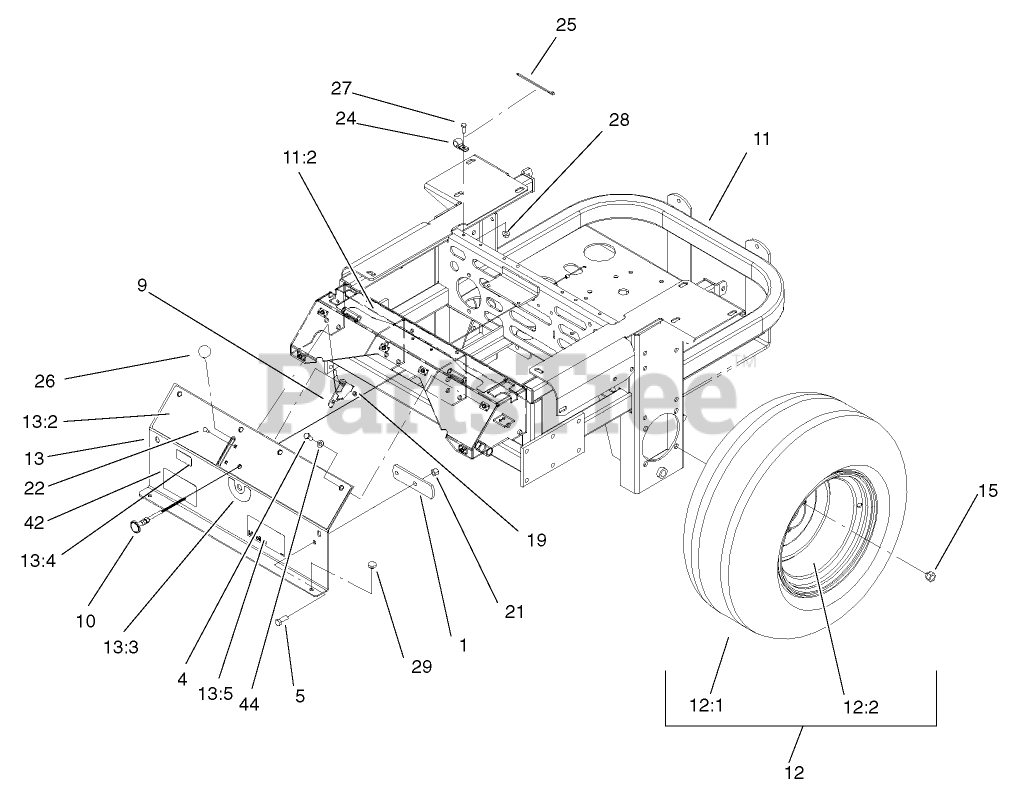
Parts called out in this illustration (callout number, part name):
1	STOP-BRAKE, PARK
4	SCREW-HH
5	SCREW-HH
9	THROTTLE CABLE ASM
10	CONTROL-CHOKE
11	Rear Frame ASM
11:2	DECAL-CONSOLE, TOP
12	WHEEL AND TIRE ASM
12:2	WHEEL RIM
13	CONSOLE ASM
13:2	DECAL-PANEL, CONTROL
13:3	DECAL-VALVE, FUEL
13:4	DECAL-PROTECTION, EAR
13:5	DECAL-MOBIL 1
15	NUT-LUG
19	NUT-LOCK, NI
21	NUT-LOCK, NI
22	BOLT-CARR
24	CLIP-LOOM
25	TIE-PLASTIC
26	KNOB-BALL
27	SCREW-HH
28	NUT-HF
29	BUMPER
42	DECAL-TORO, Z255
44	WASHER-PLAIN
